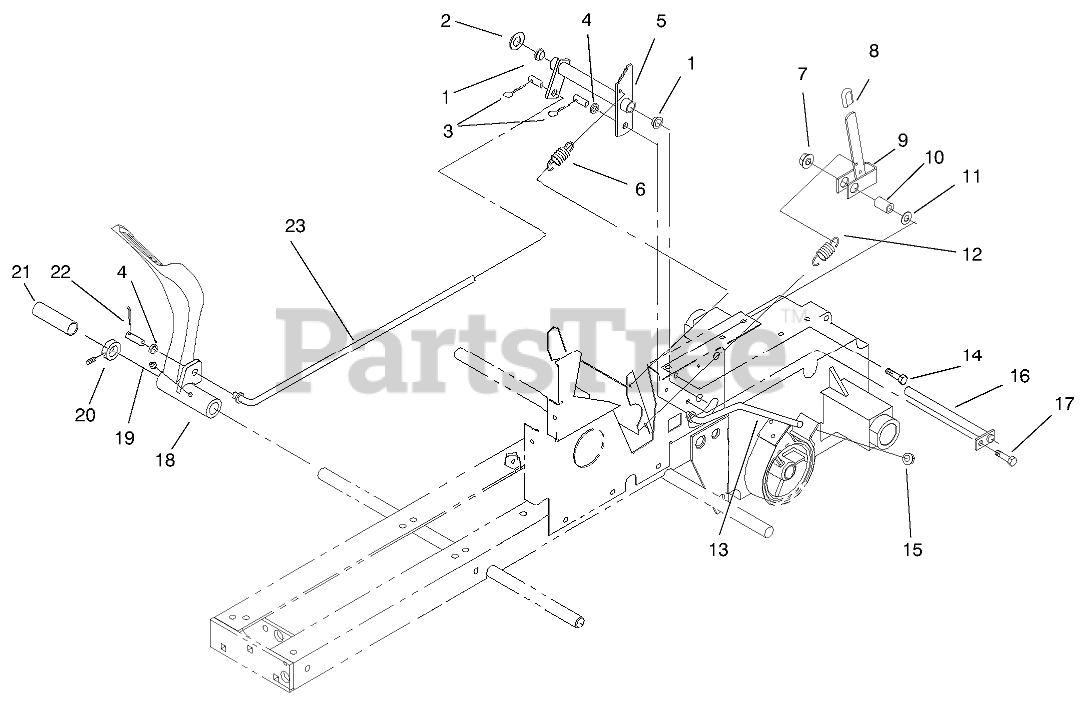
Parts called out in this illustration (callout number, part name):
1	BUSHING-FLANGED
2	WASHER-FLAT
3	PIN-HAIR
4	WASHER-NYLON
5	BELCRANK ASM
6	SPRING-EXTENSION
7	NUT-HF
8	GRIP
9	BRAKE LEVER ASM
10	SPACER
11	WASHER-FLAT
12	SPRING-BRAKE
13	ROD-REAR BRAKE
14	SCREW-HH
15	NUT-LOCK, NI
16	ROD ASM
17	Bolt
18	PEDAL-BRAKE, GEAR
19	FITTING-GREASE
20	COLLAR
21	SLEEVE-PROTECTIVE
22	PIN-COTTER
23	ROD-BRAKE
